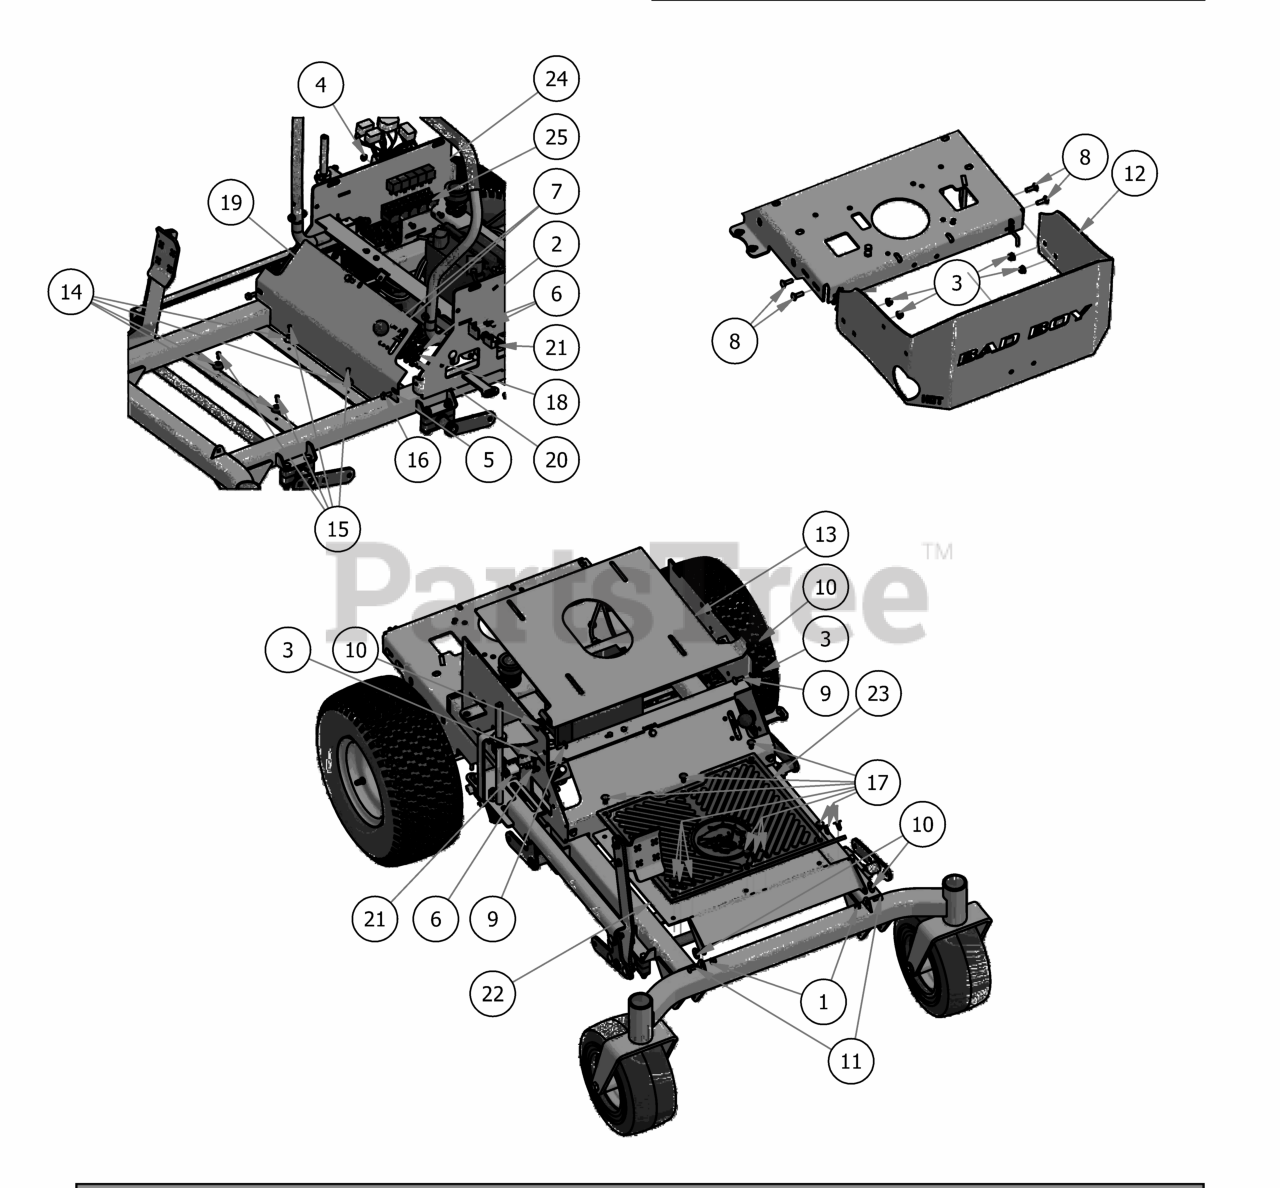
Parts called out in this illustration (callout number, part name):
1	1/4-20 Nylon Insert flange Nut
2	10-24 Nylon Insert Locknut Zinc Orange Nylon
3	5/16" Nylon Flange Nut
4	1/4-20 Hex Flange Nuts Zinc w/Serrations
5	2017 MZ Cooler Cover
6	12-24x 1/2 HWH Bolt
7	10-24 X 5/8 BS Button Head Bolt
8	5/16" x 1" Carriage Bolt
9	5/16" x 7/8" Carriage Bolt
10	.360ID Plastic Washer
11	1/4" x 3/4" Carriage Bolt
12	2017 MZ Rear Plate
13	2017 MZ Seat Plate
14	Button Bumper
15	#10 x 1/2" Self Tapping Screw
16	5/16 x 3/4 washer head type F screw
17	Ratchet Fastener
18	Universal Throttle
19	Throttle Knob
20	MZ Brake Cable
21	Safety Switch
22	MZ/ZT 2017 Floorboard
23	2017 MZ/ZT Floor Mat
25	Wiring Harness
